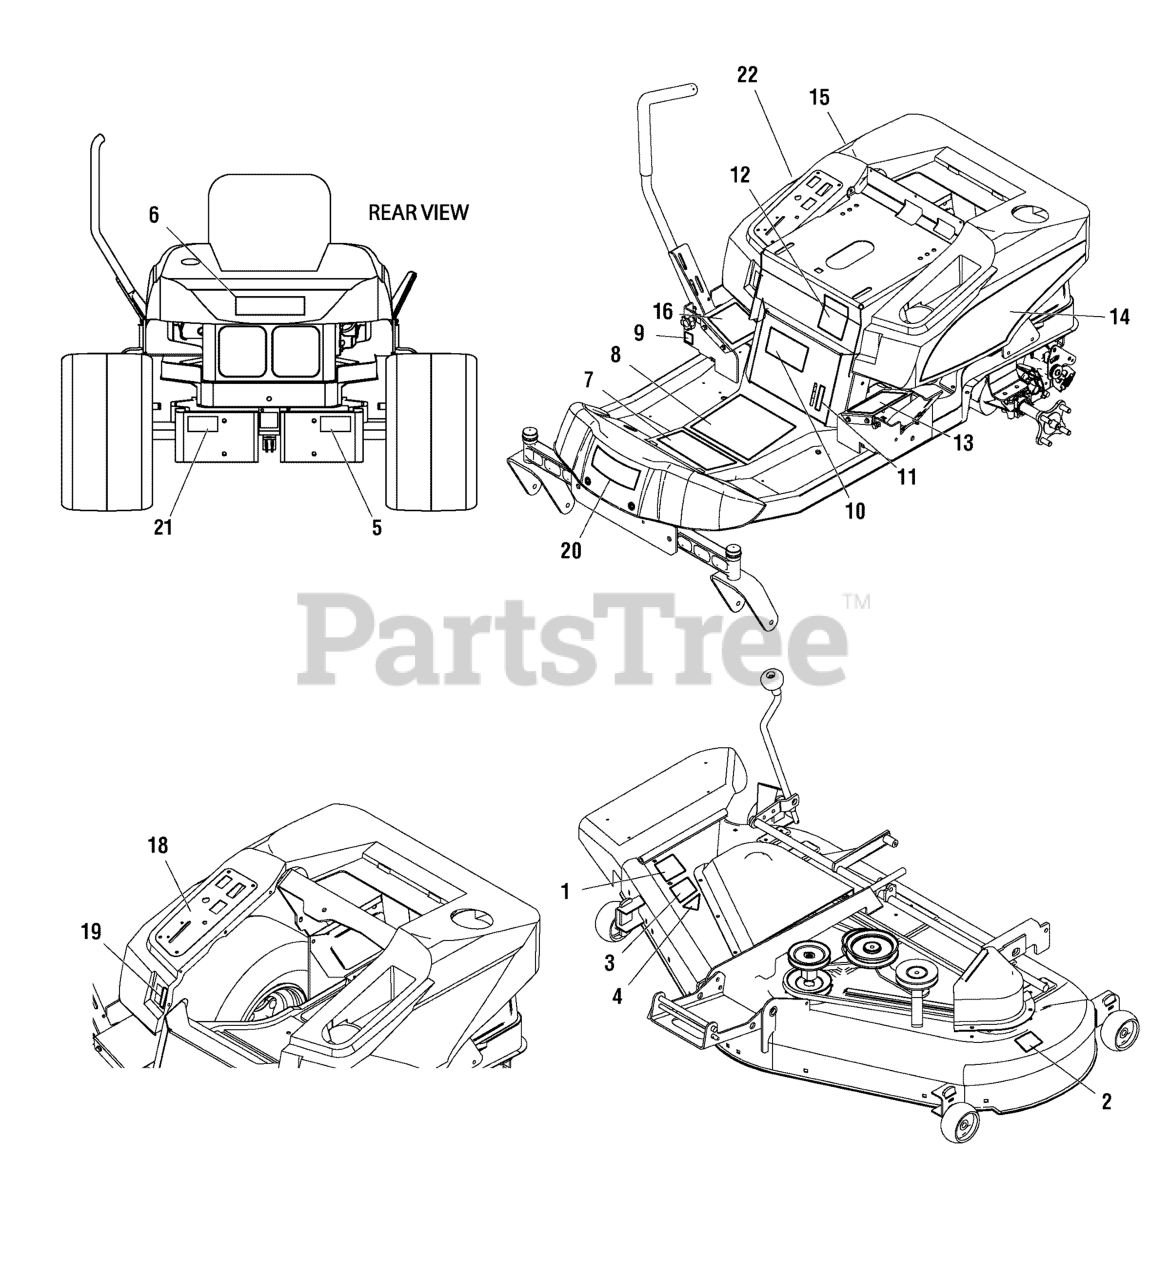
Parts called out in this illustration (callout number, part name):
1	DECAL, Danger Do Not Operate without Deflector (English/French)
2	DECAL, Danger Do Not Put Hands/Feet in Mower (English/French)
3	DECAL, 50"
4	DECAL, OPEI Certified ANSI
5	DECAL, Transmission Release Instructions (English/French)
6	DECAL, Craftsman ZTS
7	DECAL, Operator Instructions Upper (English/French)
8	DECAL, Operator Instructions Lower (English/French)
9	DECAL, Tracking Adjustment
10	DECAL, ZTS 7500 24/50
11	DECAL, Height of Cut (English/French)
12	DECAL, Service Parts B&S, 24HP
13	DECAL, Handle Control, L.H. (English/French)
14	DECAL, Seat Deck L.H. Craftsman ZTS
15	DECAL, Seat Deck R.H. Craftsman ZTS
16	DECAL, Handle Control R.H. (English/French)
18	DECAL, Instrument Panel (English/French)
19	DECAL, Height of Cut (English/French)
20	DECAL, Craftsman Logo
21	DECAL, Caution Cut Hazard
22	DECAL, Hot Surfaces (English/French)
